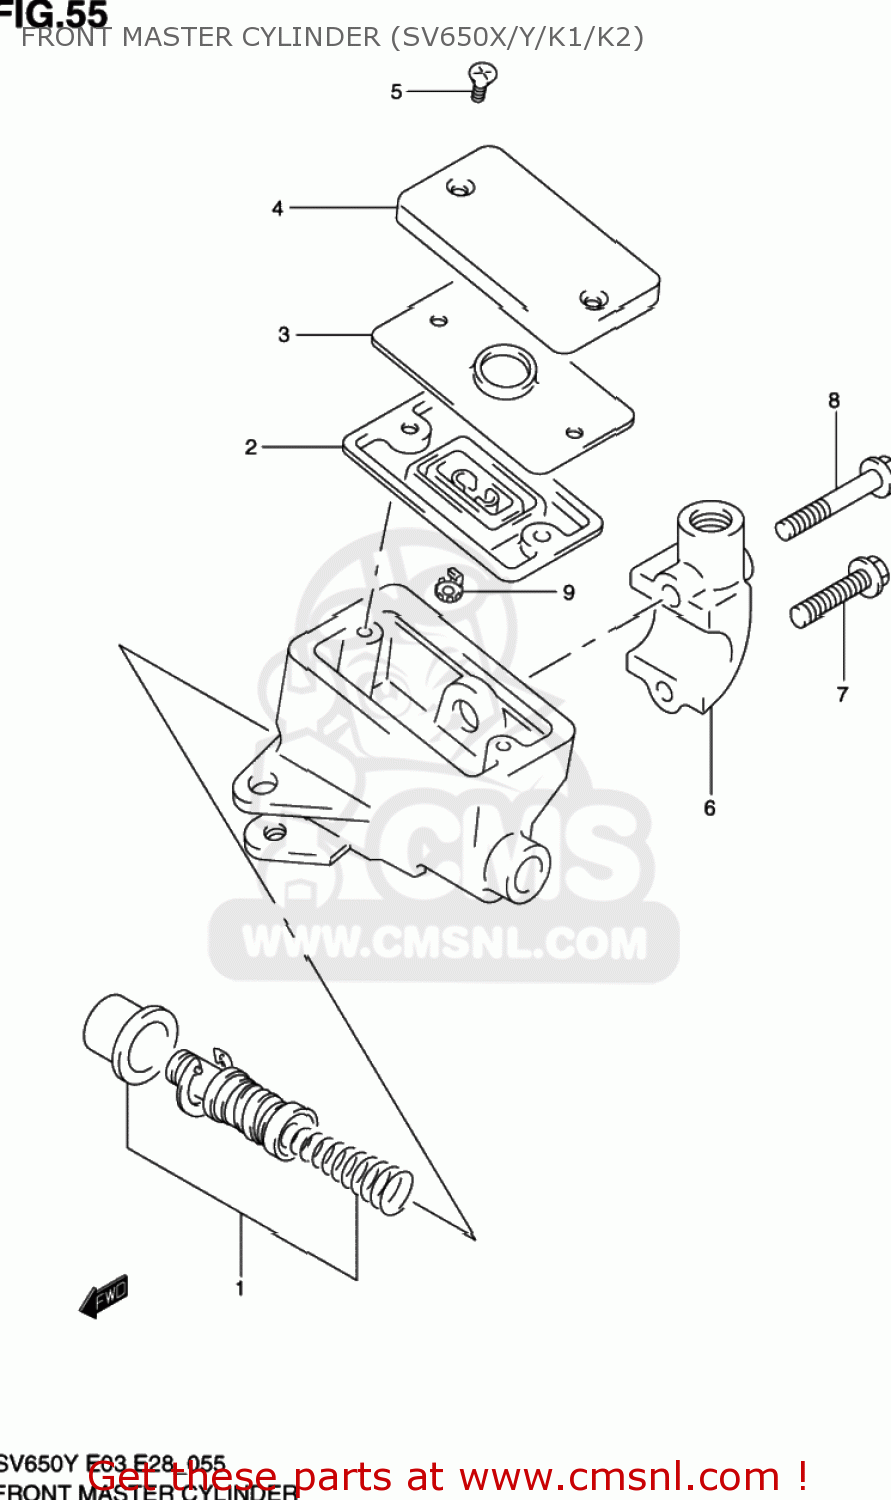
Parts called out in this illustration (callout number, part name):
1	PISTON & CUP SET
2	3
3	PLATE,DIAPHRAGM
4	CAP
5	SCREW
6	HOLDER
7	BOLT(6X25)
8	BOLT(6X38)
9	PROTECTOR
